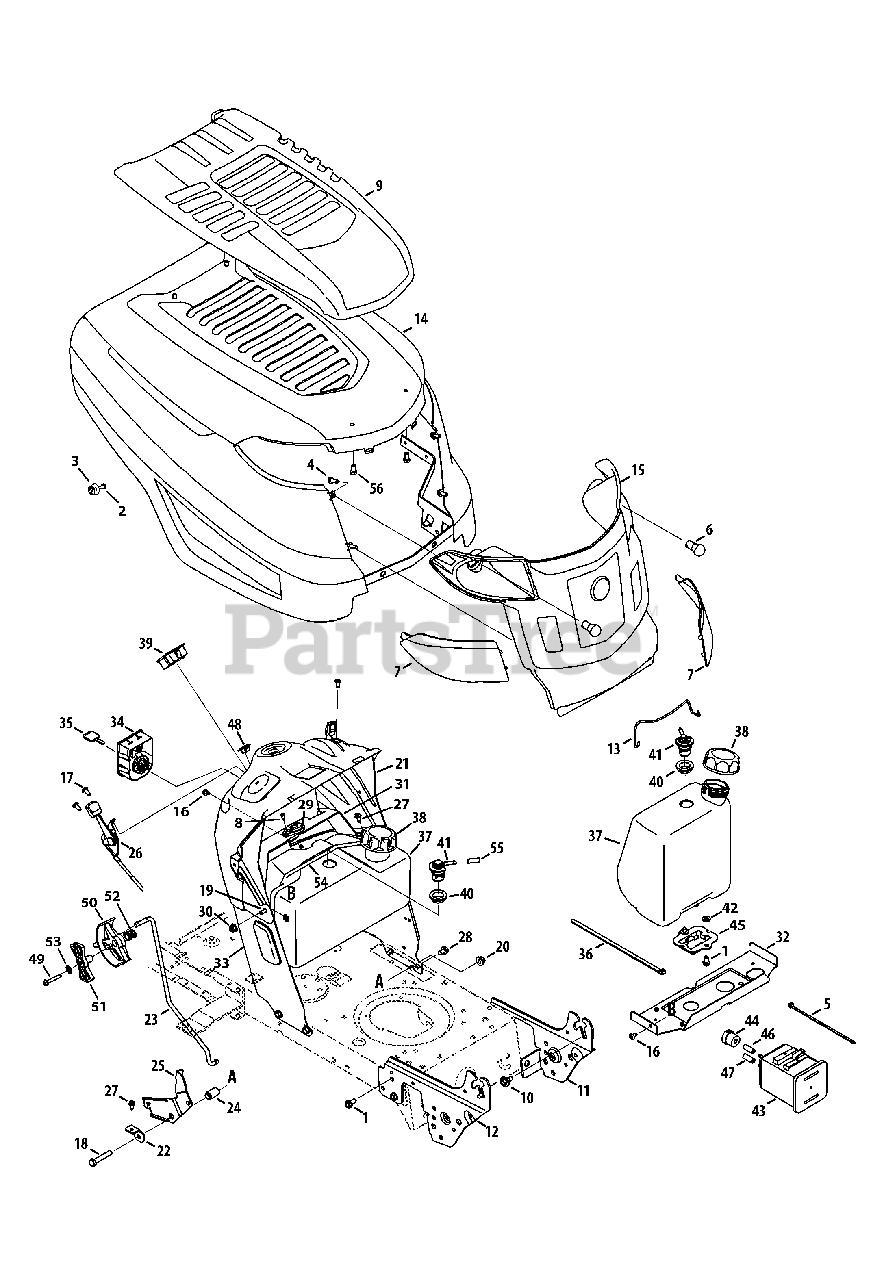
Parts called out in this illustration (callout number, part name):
1	Screw 5/16-18 x .750
2	Screw, #12-16 x 1.25
3	K-Style Bumper
4	Screw, 1/4 x .750
5	Cable Tie
6	Miniature lamp 12V socket
7	Grill Lens - LH
7	Grill Lens - RH
8	Screw, #10-16 x .500
10	Shoulder Screw .43 x .29
11	Suppport Bracket LH
12	Suppport Bracket RH
14	Hood, w/ scoop
16	Screw, 1/4-20 x .500
17	Screw 1/4-20 x .500
18	Hex Screw 3/8-16 x 2.00
19	Hex Screw, 5/16-18 x .625
20	Flange Lock Nut 3/8-16
21	Dash, Upper
22	Speed Latch Tab
23	Speed Control Rod
24	Flange Spacer .39 x .671 x 1.095
25	Transmission Speed Latch
26	Throttle/Choke Control Cable
27	Tap Screw, 1/4-20, 0.625
28	Screw 5/16-18 x .625
29	Bearing, .628 ID x 1.36
30	Flange lock Nut 5/16-18
31	Bracket, Steering Support
32	Gas Tank Support Bracket
33	Dash, Lower
34	Key Switch Module
35	Key, Assembly
36	Cable Tie
37	Fuel Tank, 2 Gallons, EPA
37	Fuel Tank, 1.36 Gallon, CARB
38	Fuel Cap
38	Fuel Cap, CARB
39	Ammeter Monitor Indicator
40	Rubber Grommet
41	Rollover Valve
42	Washer, Flat, .344 x .750 x .120
43	Canister, Carbon, 5 Gallon
44	Filter, Vent, Canister
45	Bracket., Adapter, Canister
46	Hose, Fuel, Low Perm., White
47	Hose, Fuel, Low Perm., Yellow
48	Choke Plug
49	Hex Washer Screw, 1/4-20 x 1.50
50	Shift Lever
51	Index Control
52	Compr. Spring, .685 OD x .63
53	Lock Washer, 1/4
54	Fuel Tank Clamp Rod
55	Hose Vent, 3/16 EPA
56	Screw, 1/4-15 x 0.50
